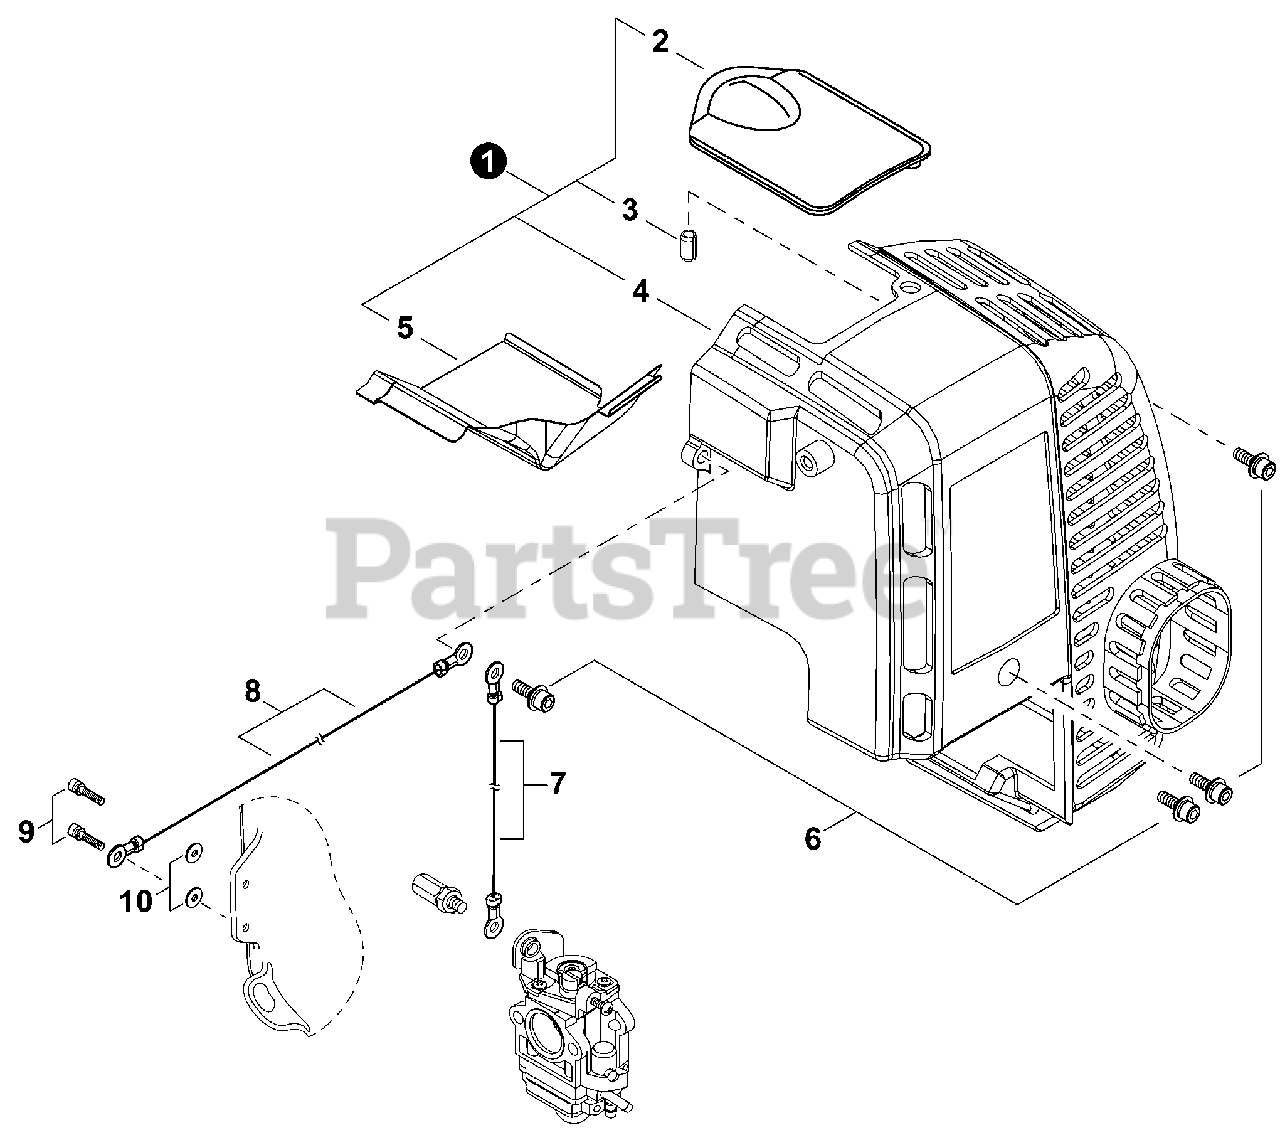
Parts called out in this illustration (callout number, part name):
1	COVER ASSY, ENGINE
2	COVER, SPARK PLUG
3	PIN, SPRING 4×8
4	COVER, ENGINE
5	HEAT SHIELD, EXHAUST
6	BOLT M5×16
7	WIRE, STATIC DISCHARGE 110 MM
8	LEAD 0.75 MM2 L= 590
9	BOLT, ADHESIVE M5×18
10	WASHER Ø15ר5.2×1.6
